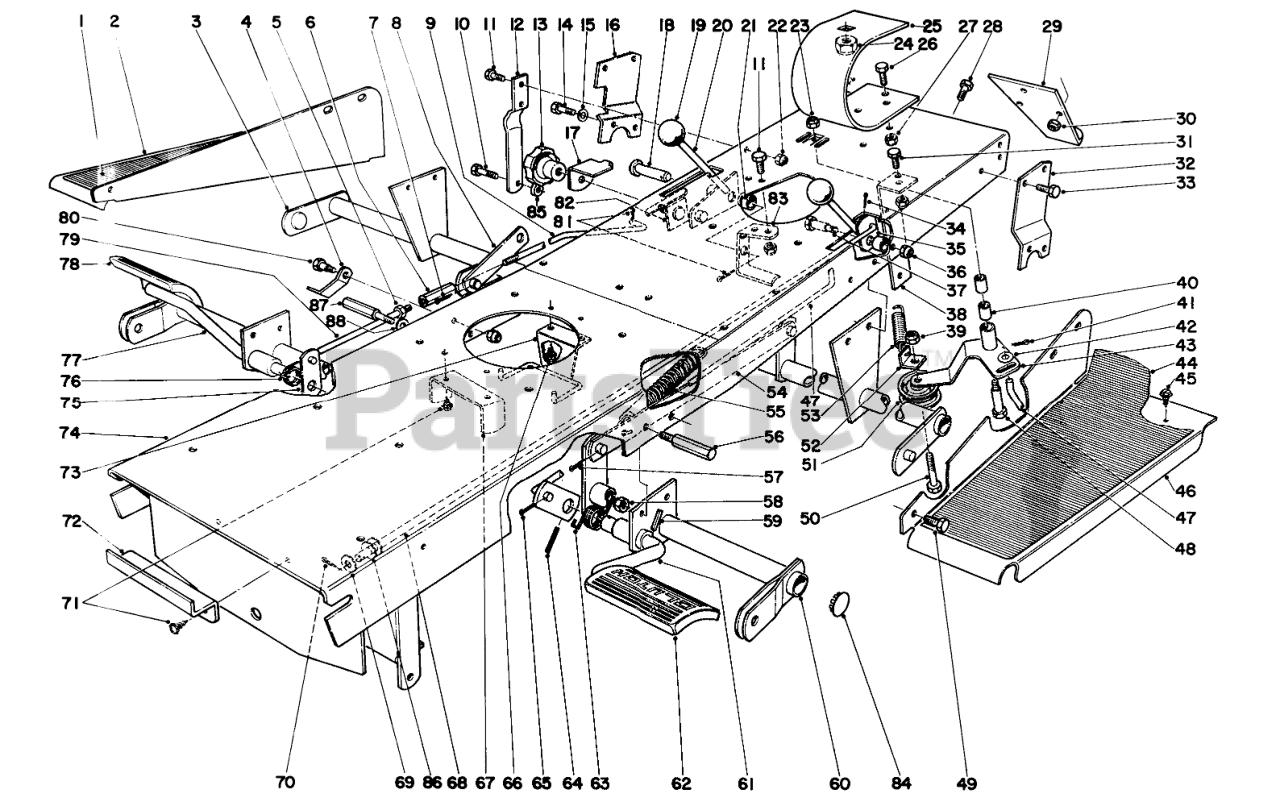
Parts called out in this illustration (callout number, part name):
1	Pad R. H.
2	Footrest R.H.
3	Cross Tube Rear
4	Pedal Latch
5	NUT-JAM
6	Screw Brake Adjusting
7	PIN-COTTER
8	Lift Link
9	Brake Rod Rear
10	SCREW-HH
11	SCREW-HH
12	Brake Hanger
14	SCREW-HH
15	WASHER-LOCK
16	Support Right
17	Slide
20	Lever
21	Spacer
22	Nut
25	Seat Spring
26	SCREW-HH
28	SCREW-HH
29	Hitch
31	SCREW-HH
32	Support Left
33	SCREW-HH
34	PIN-COTTER
35	Lever
37	Shoulder Bolt
38	Support Transaxle
40	Bushing
41	PIN-COTTER
42	WASHER-FLAT
43	Idler Arm Incl. Ref. #36
44	Pad Left
45	Self Tapping Screw
46	Footrest
47	Clutch Rod
48	Shoulder Bolt
49	SCREW-HH
50	SCREW-HH
51	Pulley
53	Tension Spring
54	Lift Equalizer
55	Spring Counterbalance
56	Pedal Stop
57	PIN-COTTER
58	Nut
59	PIN-SPRING
60	Cross Tube Front
61	Pedal L.H.
62	CLUTCH PAD
63	Pedal Return Spring
64	RollPin
65	PIN-COTTER
66	10-32 X 1/2 PHILLIPS
67	Cutter Guide
68	Rod Clutch
69	WASHER-FLAT
70	PIN-COTTER
71	10-32 X 1/2 PHILLIPS
72	Spring Clip
73	Belt Traction Guide
74	Frame
75	Lever Pedal Shaft
76	Pedal Return Spring
77	Pedal Right
78	PAD-BRAKE
79	Brake Rod Front
80	Shoulder Bolt
81	PIN-COTTER
82	Knob Plate
83	Support Guide
84	Plug Button
85	Spacer
86	GRILLE HINGE SPACER
87	Brake Stop
88	Washer
